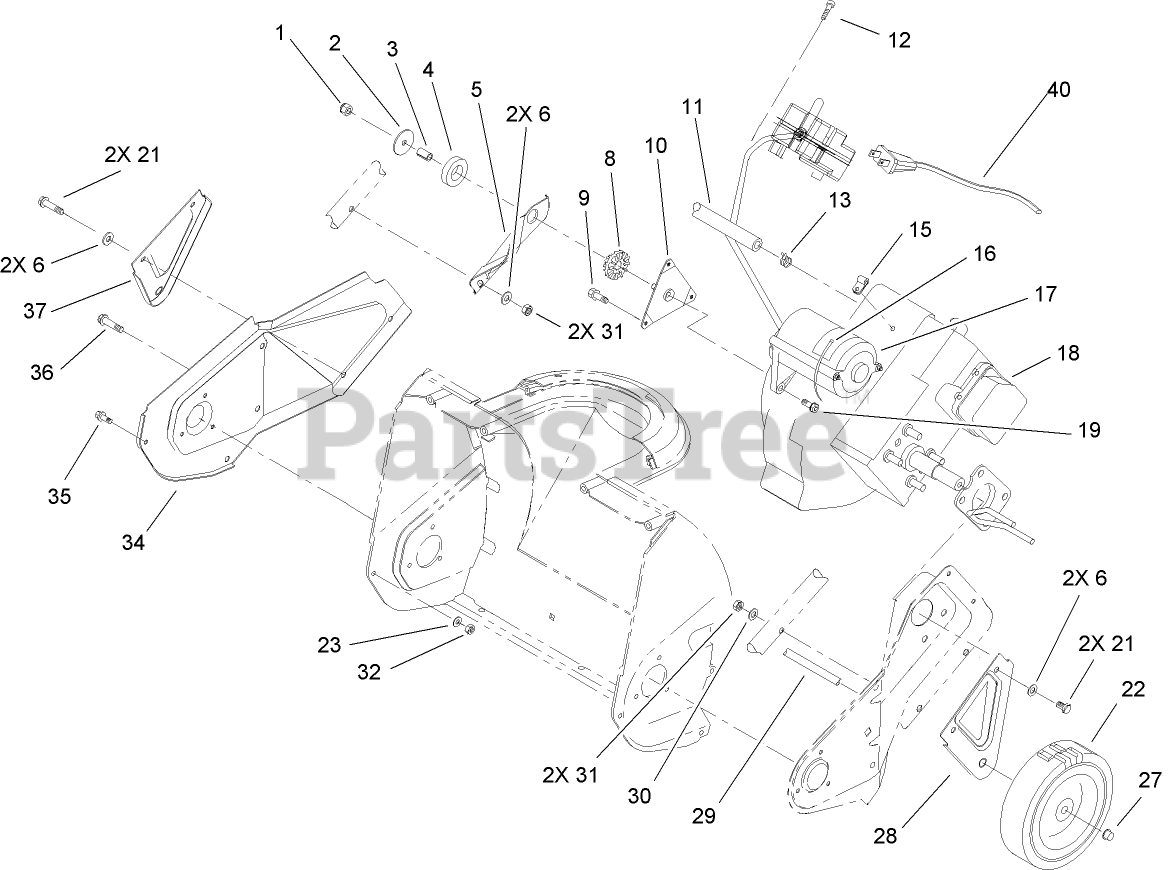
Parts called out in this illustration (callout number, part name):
1	NUT-LOCK, NI
3	SPACER-TUBULAR
4	RING-ISOLATOR
5	BRACKET-SUPPORT, ENGINE
6	WASHER-FLAT
8	BUSHING-ISOLATOR
9	SCREW
10	BRACKET AND STUD ASM
11	HOSE-FUEL
12	SCREW-PLASTITE
13	CLAMP-HOSE
15	CLAMP
16	TIE-CABLE
18	Loose Parts Package
19	SCREW-HH, TORX
21	SCREW-HH
22	WHEEL
23	WASHER-FLAT
27	NUT-PUSH
28	BRACKET-WHEEL, LH
29	AXLE SHAFT
30	WASHER
31	NUT-LOCK, NI
32	NUT-LOCK, NI
34	PLATE-SIDE, RH
36	SCREW-PLASTIC
37	BRACKET-WHEEL, RH
40	CORD-ELECTRIC
